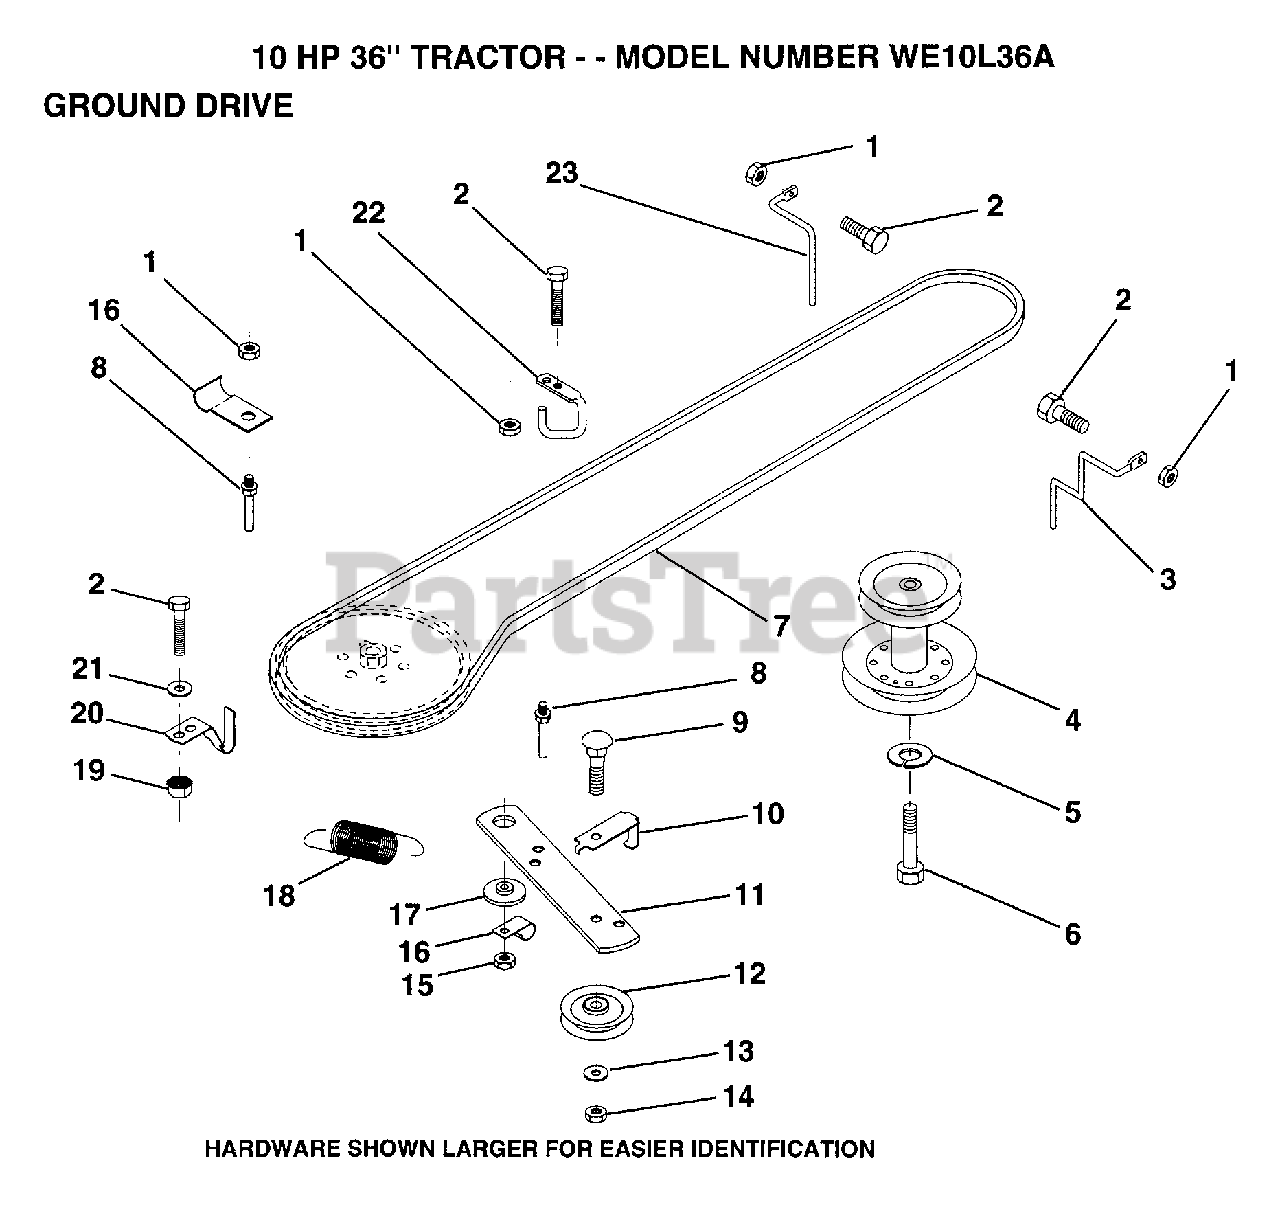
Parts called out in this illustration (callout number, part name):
2	BOLT
5	LOCKWASHER
6	HEX BOLT
7	BELT
8	"KEEPER,DRIVE BELT"
9	BOLT
10	"KEEP,IDLER DR BEL"
12	PULLEY IDLER
13	WASHER
14	LOCKNUT
16	"CLIP,INSULATOR"
17	SPACER RETAINER
20	"KEEPER,DR BELT "
21	WASHER
22	"KEEPER,FRA DR BEL"
